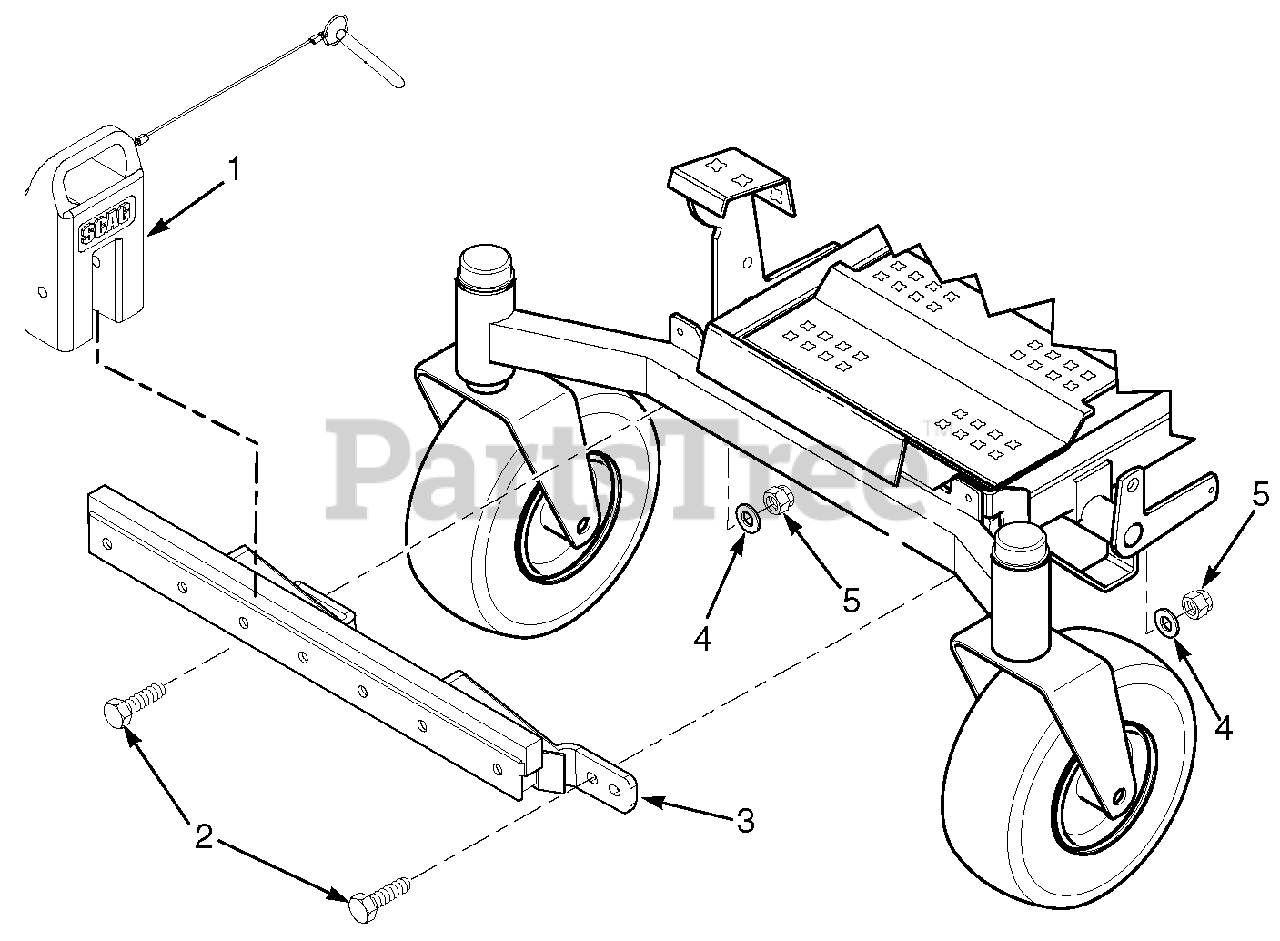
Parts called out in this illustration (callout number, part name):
1	Weight Assembly
2	Bolt, Hex Head 7/16-14 x 1-3/4"
3	Support Weldment, Weights
4	Flatwasher, 7/16-.500 x 1-1/4"
5	Nut, Elastic Stop 7/16-14
